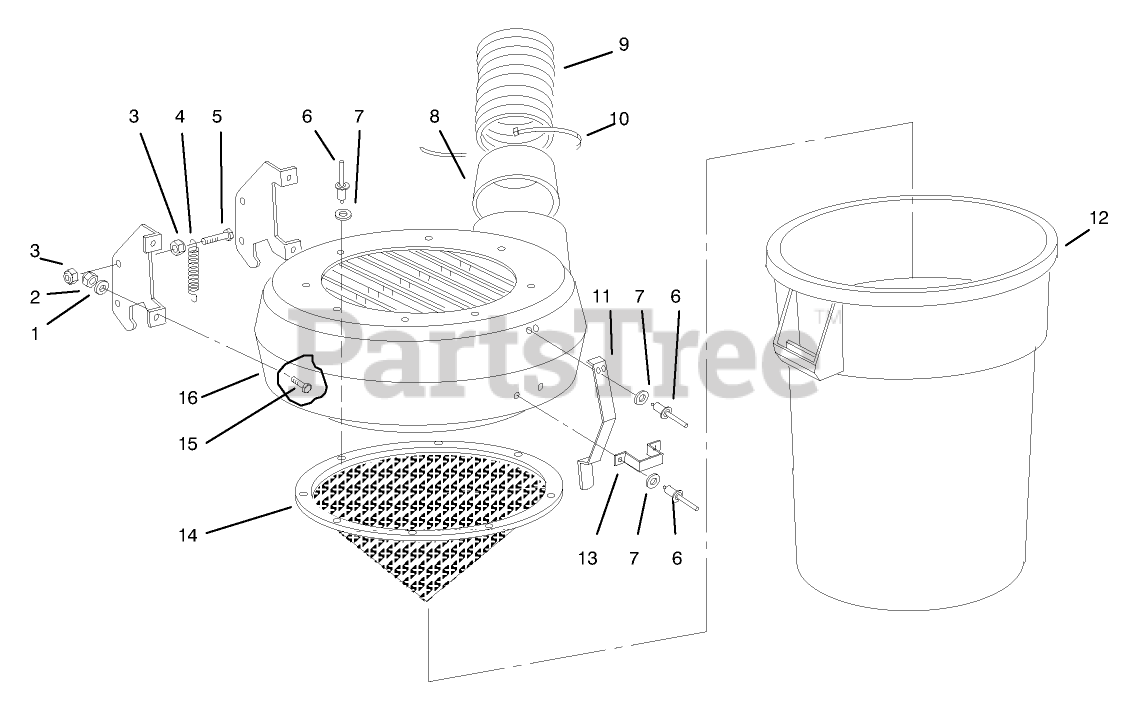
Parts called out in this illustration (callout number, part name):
1	WASHER-PLAIN
2	NUT-LOCK, NI
3	NUT-HEX
4	SPRING-EXTENSION
5	SCREW-HH
6	RIVET-POP
7	WASHER-FLAT
8	SEAL ASSEMBLY NP
9	HOSE 6" X 48"
11	LATCH-BAGGER TOP B
12	CANISTER
13	BRACKET B
14	SCREEN-BAGGER TOP
15	SCREW-HH
16	TOP-CANISTER
